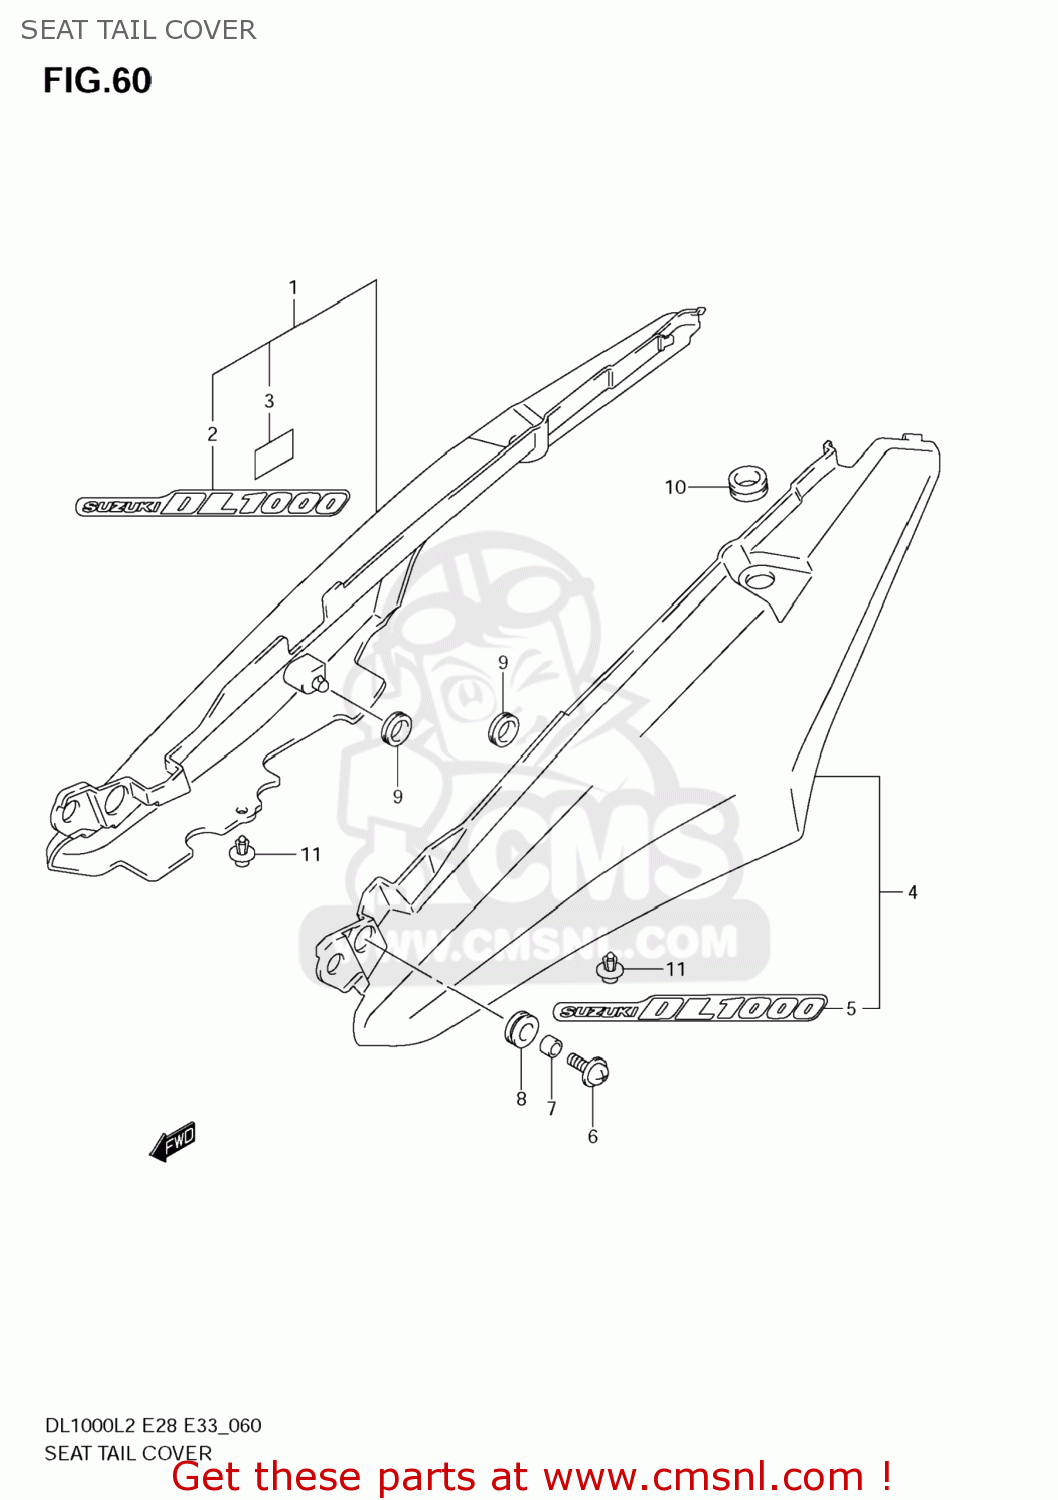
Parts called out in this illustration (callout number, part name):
1	COVER,SEAT TAIL,R(BLACK)
2	EMBLEM,SEAT TAIL COVER
3	PROTECTOR,FRAME COVER
4	COVER,SEAT TAIL,L(BLACK)
5	EMBLEM,SEAT TAIL COVER
6	SCREW(6X20)
7	SPACER(6.5X12X9)
8	CUSHION
9	CUSHION
10	CUSHION
11	CLIP(BLACK)
